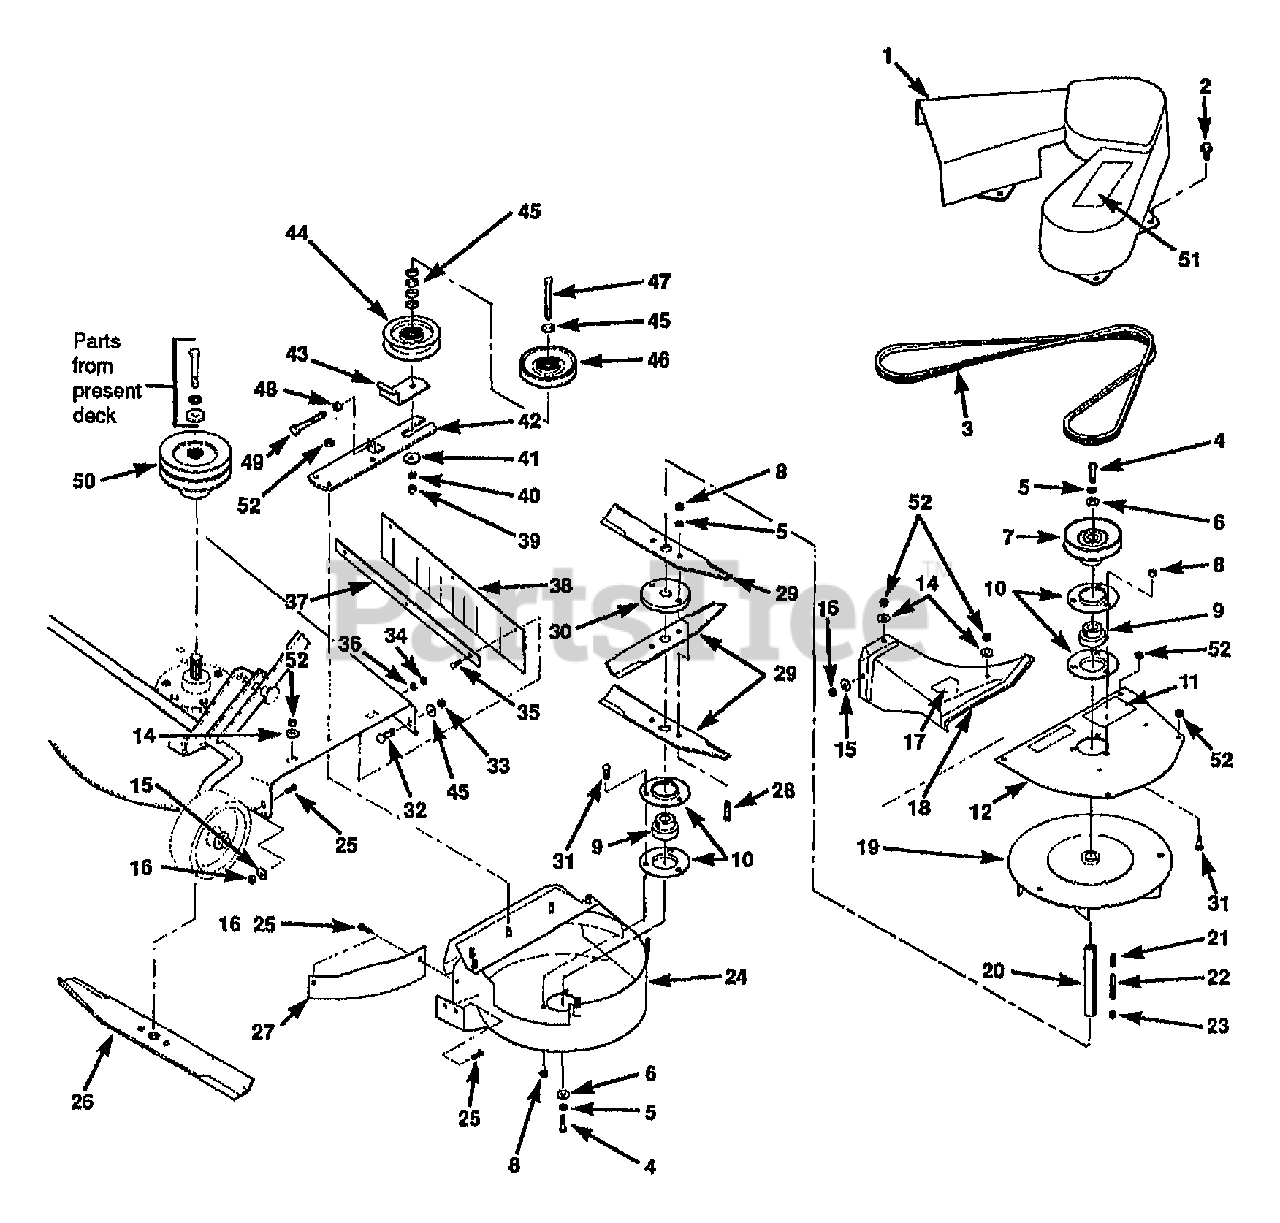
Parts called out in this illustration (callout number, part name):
1	COVER-BELT
2	SCR-THRD FRM 1/4-14X.50
3	BELT-DRIVE
4	SCR-HH 5/16-18X1.0 G5 ZP
5	WASHER-LK .312 ZP
6	WASHER-.312 X 1.378
7	SHEAVE-DRIVEN
8	NUT-TOP/LK 5/16-18 ZP
9	BEARING-BALL
11	DECAL-BELT INSTALLATION
12	COVER-HOUSING
14	WASHER-FLAT 5/16 SAE
15	WASHER-FLAT 1/4 SAE
16	NUT-HF/LK 1/4-20 ZP
17	DECAL-OPEI CAUTION
18	DEFLECTOR-DISCH W/DECAL
21	KEY-.188 SQ X 1.0
22	KEY-.188 SQ X 2.0
23	KEY .188 SQ X.343
24	ASSM-HOUSING
25	SCR-CARR 1/4-20X.75 G2 ZP
26	BLADE-MWR LH HILIFT
27	BAFFLE-REAR
28	SCR-HH 5/16-18X1.25 G5ZP
29	BLADE-11.375"
30	HUB-BLADE
31	SCR-CARR 5/16-18X.62 G2 ZP
32	BOLT-3/8-16 X 3/4
33	NUT-HFLK 3/8-16 ZP
34	NUT-HEX M10-24
35	SCR HFLK #10-24X.75 ZP
36	WASHER-LK M10
37	STRIP-RETAINER
38	SHIELD-DEFLECTOR
39	NUT-HEX 3/8-16 ZP
40	WASHER-LK .375 @ DEPL
41	WASHER-FLAT 1.25X.406X.179
42	ASSM-IDLER BRACKET
43	BRKT-ADJUSTMENT
45	WASHER-FLAT 3/8 SAE
46	PULLEY-IDLER
47	SCR-HHC 3/8-16X3.25
48	NUT-HEX 5/16-18 ZP
49	SCR-HHM 5/16-18X2.75
50	PULLEY-DRIVE DUAL GROOVE
51	DECAL-IDENTIFICATION
52	NUT-HFLK 5/16-18 ZP
